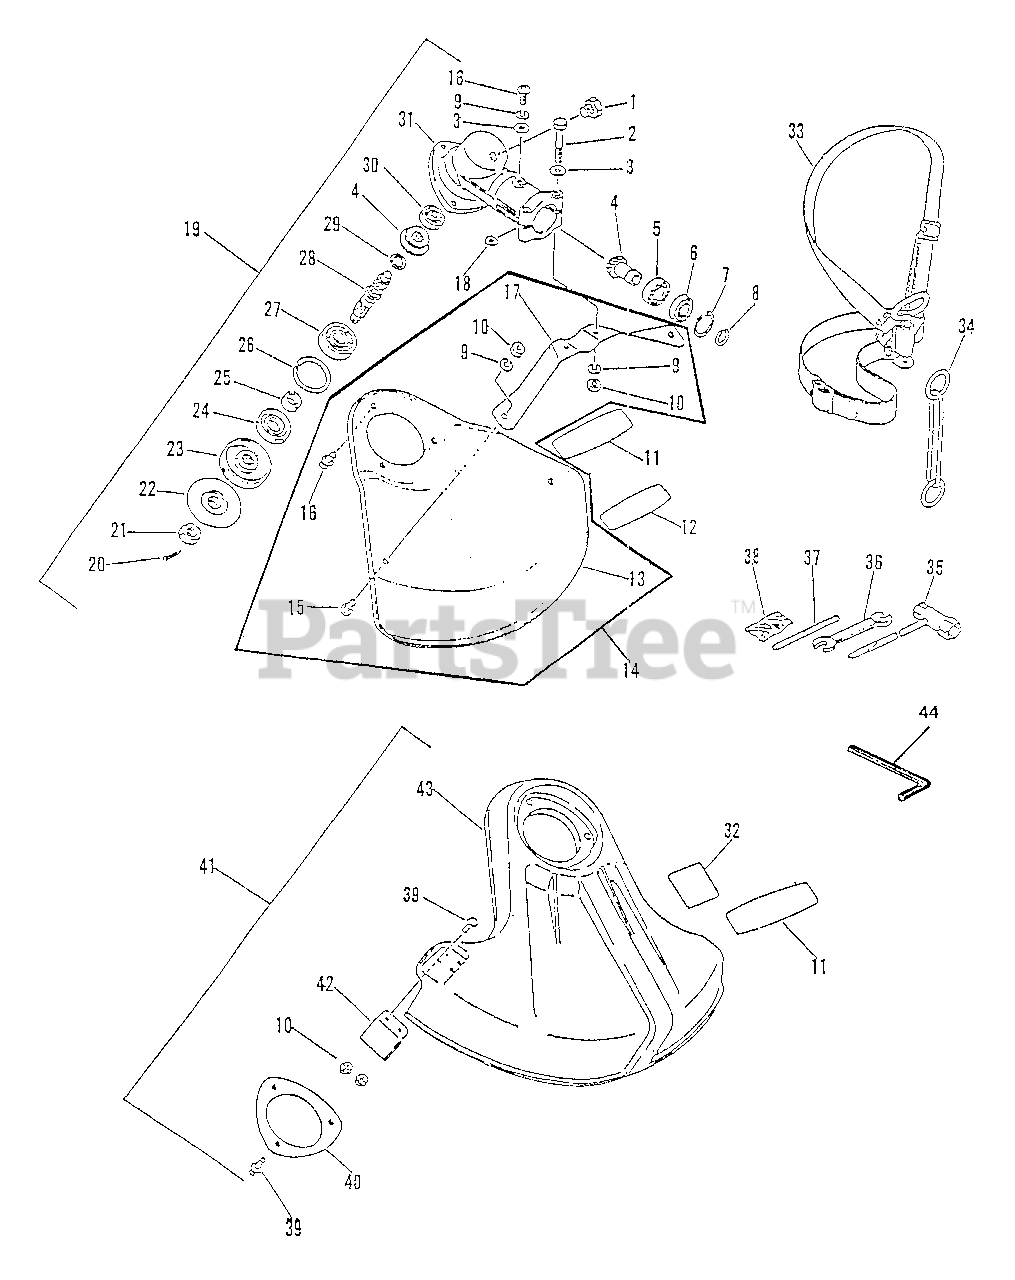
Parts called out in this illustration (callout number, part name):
1	BOLT - 8X8
2	BOLT - 5X35
3	WASHER - 5
4	GEAR SET - BEVEL
5	BEARING, BALL - 6900
6	BEARING, BALL - 6900Z
7	RING, RETAINING - 22
8	RING, RETAINING - 12
9	LOCKWASHER - 5
11	LABEL - LESCO
12	LABEL - CAUTION
13	SHIELD, DEBRIS - METAL
14	DEBRIS SHIELD KIT - METAL
15	SCREW - 5X8
16	SCREW - 5X10
17	BRACKET, SHIELD
19	GEAR CASE ASSY
20	PIN, SPLIT - 2X22
21	NUT - 10 -- LEFT HAND
22	ADAPTOR, BLADE - LOWER
23	ADAPTOR, BLADE - UPPER
24	SEAL, OIL
26	RING, RETAINING - 32
27	BEARING, BALL - 6201
28	GEAR - SHAFT
29	RING, RETAINING - 10
30	BEARING, BALL - 609
31	CASE, GEAR
32	LABEL - CAUTION
33	SHOULDER STRAP ASSY
35	T-WRENCH - 17X19mm
36	SPANNER - 8X10mm
37	LOCKING TOOL
38	PIN, SPLIT - 2X22
39	SCREW - 5X16
40	PLATE, SHIELD
41	DEBRIS SHIELD KIT
42	KNIFE, TRIMMER LINE
43	SHIELD, DEBRIS - PLASTIC
44	HEX KEY - 3mm
